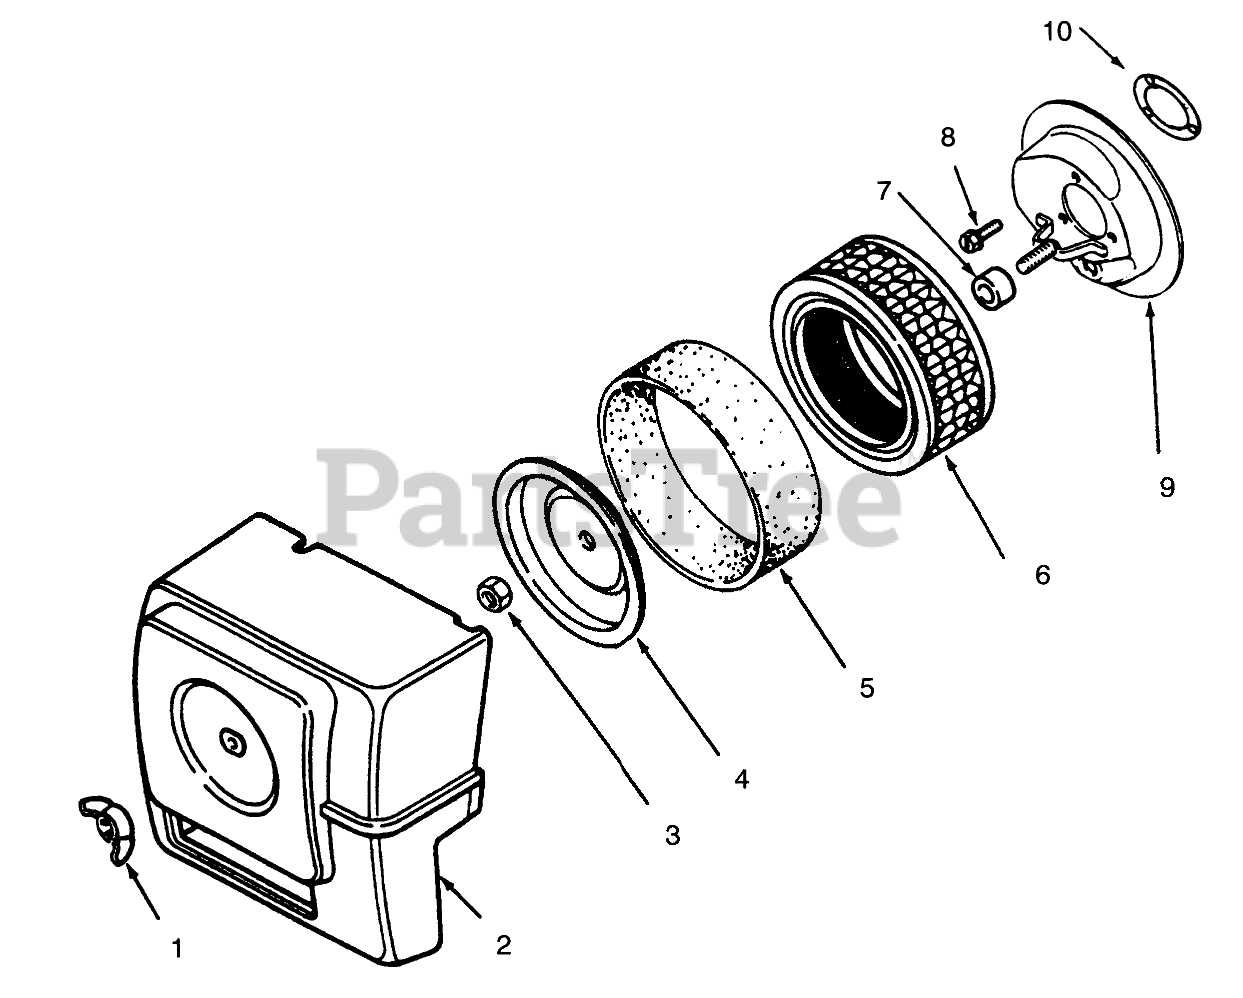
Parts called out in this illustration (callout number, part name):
1	Nut-Wing
2	Cover
4	Air Cleaner Element Cover
5	Element-Precleaner
6	Element
8	Screw
9	Base-AirCleaner
10	Gasket
